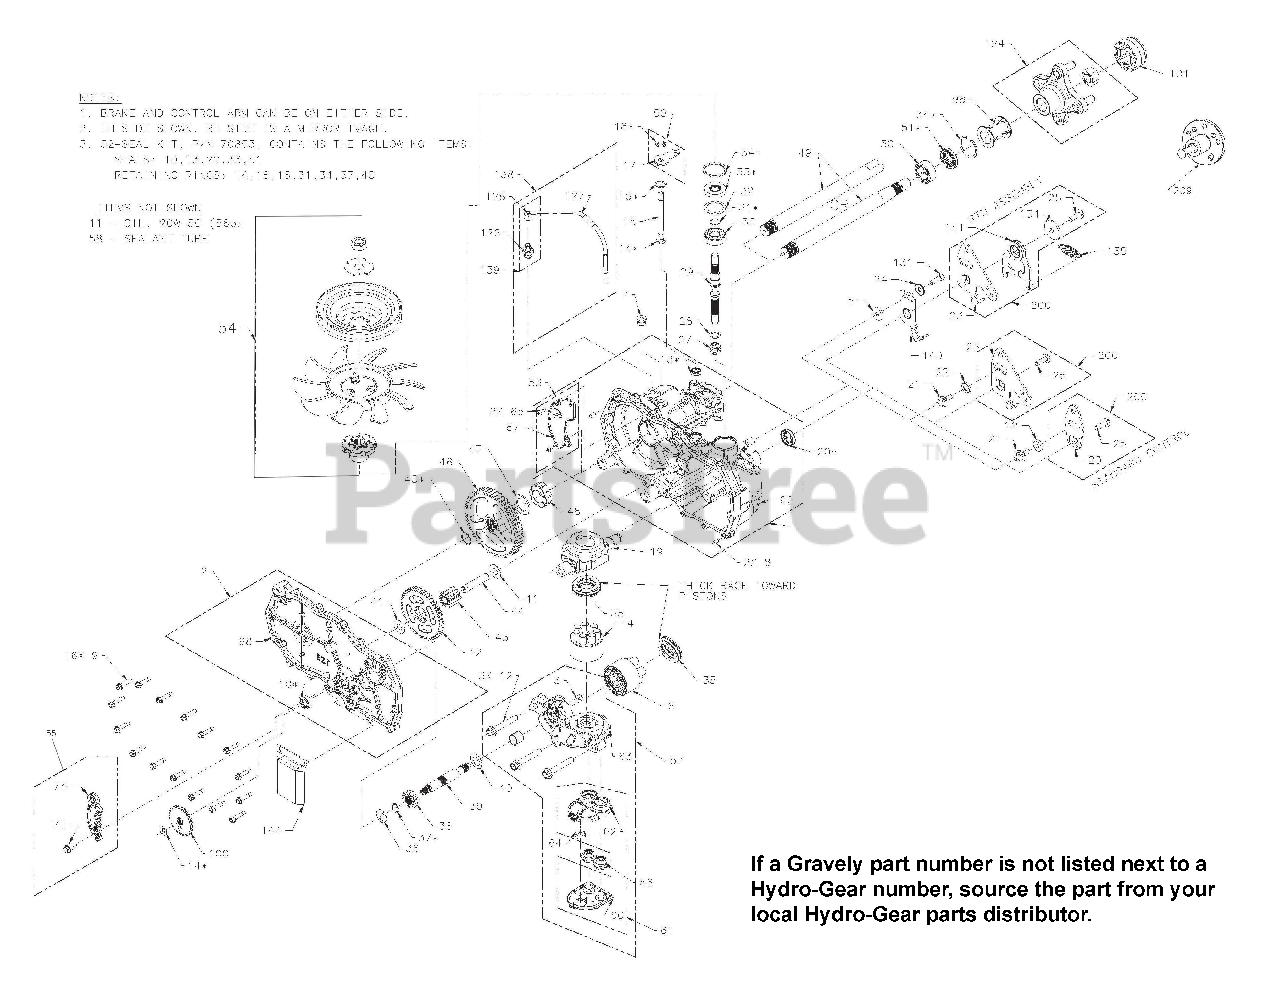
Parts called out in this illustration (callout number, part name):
1	ASSEMBLY, MAIN HOUSING-LH
2	HG (70863R)
4	ASSY, BLOCK 7 PISTON
5	SPACER
6	KIT, 10 CC BLOCK
9	SCREW,HEX WASHER 1/4-20X1.125
14	RING, RETAINING .375 EXT
15	ROD, BYPASS
16	RING, RETAINING .750 INT
18	RING, RETAINING .375 EXT
19	TRUNNION, SWASHPLATE
24	WASHER
27	SPRING. BLOCK
28	WASHER. THRUST .59 X .79 X .04
29	SHAFT, INPUT
30	BRG, BALL 17X40X12
31	RING, RETAINING WIRE .561 ID
32	WASHER 1.23X1.56X.04
34	RING, RETAINING
35	BEARING. THRUST 30 X 52 X 13
36	WASHER .63X1.0X.05
37	RING, RET 62 EXT
38	GEAR, 13T PINNION
39	SHAFT, MOTOR
40	WASHER .71 X 1.16 X .04
41	WASHER .5X1.0X.032
42	GEAR, 10T/48T
43	GEAR, 10T JACKSHAFT
44	JACK SHAFT (PIN)
45	RING, SPIRAL RETAINING
46	GEAR, 52T BULL
48	SLEEVE BEARING
49	SHAFT, AXLE
52	KIT, SEALS AND RETAINING
53	KIT, EXPANSION PLATE RH
54	FAN PULLEY KIT 4.5X1.625
55	BRAKE ARM, EZT #70865
57	KIT, CENTER SECTION, W/FILTER - LH
58	SEALANT TUBE 10.1OZ.
59	KIT, BYPASS ARM
61	KIT, FILTER
98	TUBE, AXLE
100	DISC, COG BRAKE
101	CAP, AXLE
124	KIT, HUB 4 BOLT
131	KIT, RTN SCREWS
135	SPRING, EXTENSION
138	KIT, BREATHER ASSEMBLY
139	KIT, BREATHER ASSEMBLY
140	ARM, NEUTRAL RIGHT
200	KIT, RTN, BIDIRECTIONAL
209	HUB PULLER 4 BLT HYDGEAR 71459
